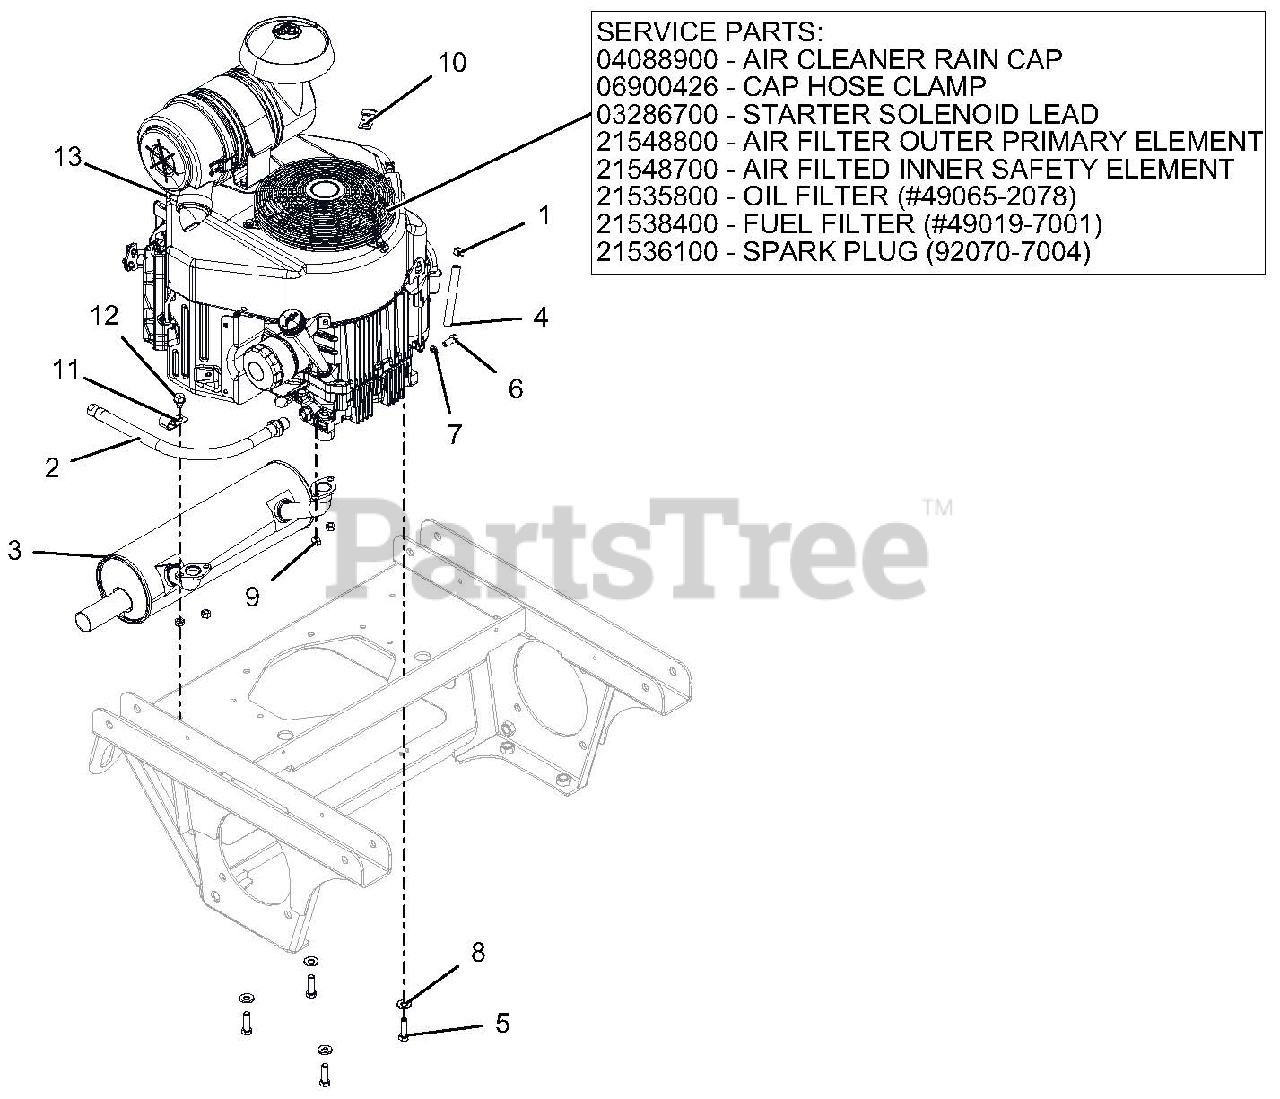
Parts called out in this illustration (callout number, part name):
1	CLAMP, FUEL LINE
2	HOSE, OIL DRAIN
3	MUFFLER, KAWASAKI FX24/26 HP
4	.25 LOW-PERM GAS HOSE 20.00" LG - VALVE TO ENGINE
5	BLT-HEX .38-16X1.25 GR5 YWZC NYTORQ
6	@BLT-HEX M8-1.25X20 YWZC
7	WSHR-LK .31X.078 REG YWZC
8	WSHR, 3/8" SPRING DISC
9	NUT-LK-TOP M8-1.25 YWZC
10	CLAMP, J
12	SCR-TAP .38-16X.50 HWH TR YWZ
13	ENGINE, KAWASAKI FX730
13	AIR CLEANER RAIN CAP
13	CAP HOSE CLAMP
13	STARTER SOLENOID LEAD
13	AIR FILTER OUTER PRIMARY ELEMENT
13	AIR FILTER INNER SAFETY ELEMENT
13	OIL FILTER
13	FUEL FILTER
13	SPARK PLUG
